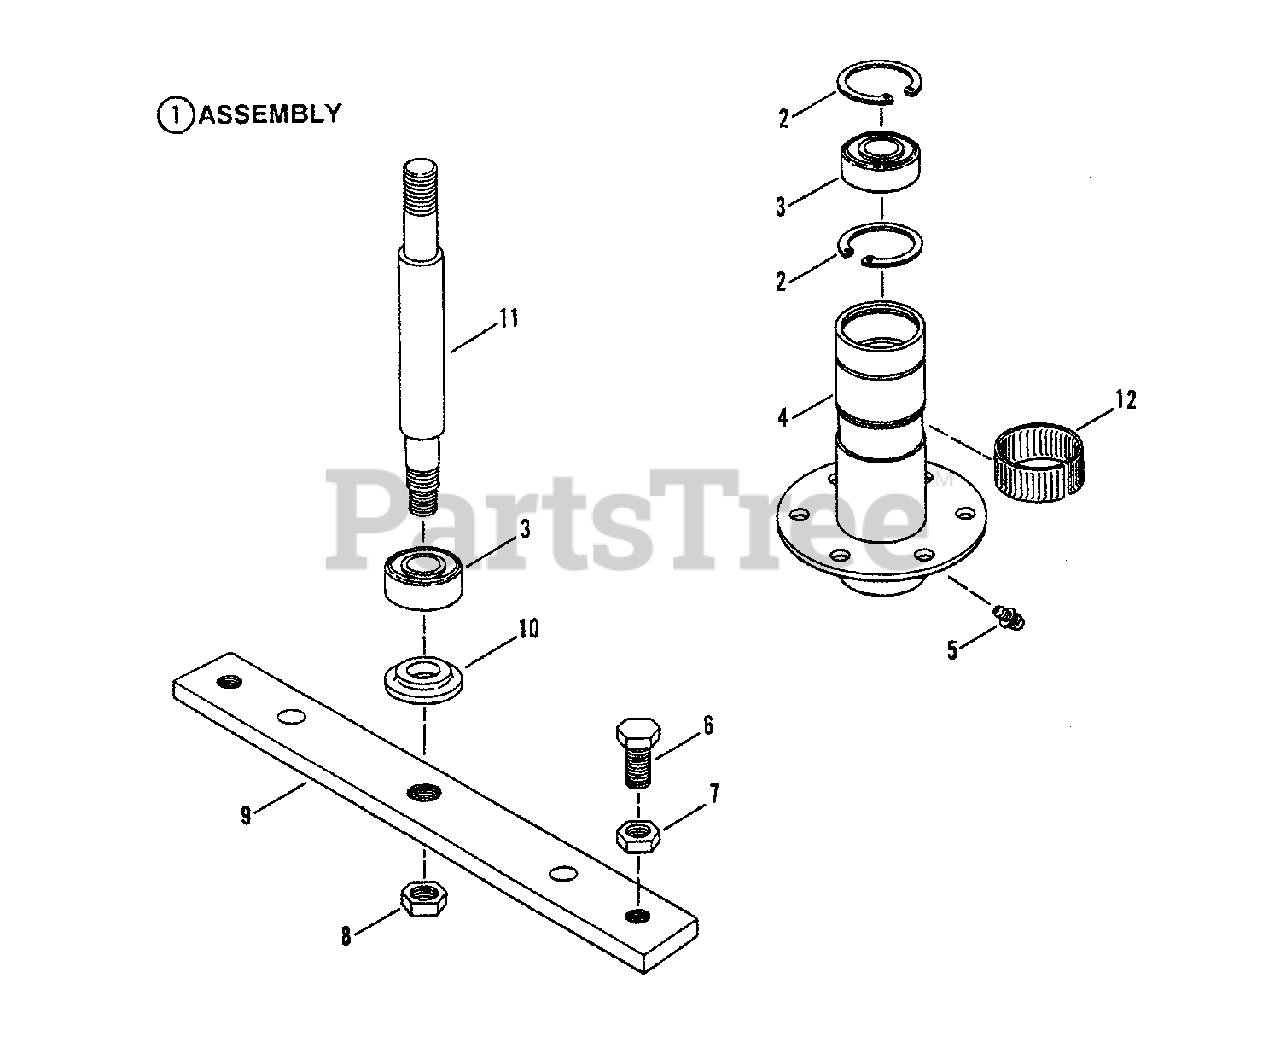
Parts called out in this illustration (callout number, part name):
1	ASSEMBLY, Spindle Housing, 33" Cutting Deck (Incl. items 2 thru 11)
2	RING, 1-3/4" Retaining
3	BALL BEARING, 3/4" I.D.
4	WELDMENT, Spindle Housing (Includes Item 5)
5	FITTING, Lube (Press fit for .187 hole-no ball)
6	SCREW, 1/2-20 x 1-1/4" Hex Head Cap, GR5
7	NUT, 1/2-20 Hex Jam
8	NUT, 5/8-18 Hex Center Lock Jam, GR5 or B
9	HOLDER, Blade
10	WASHER, Spindle
11	SPINDLE, 4" Shoulder, 7.54" Long
12	RING, 2" Tolerance
